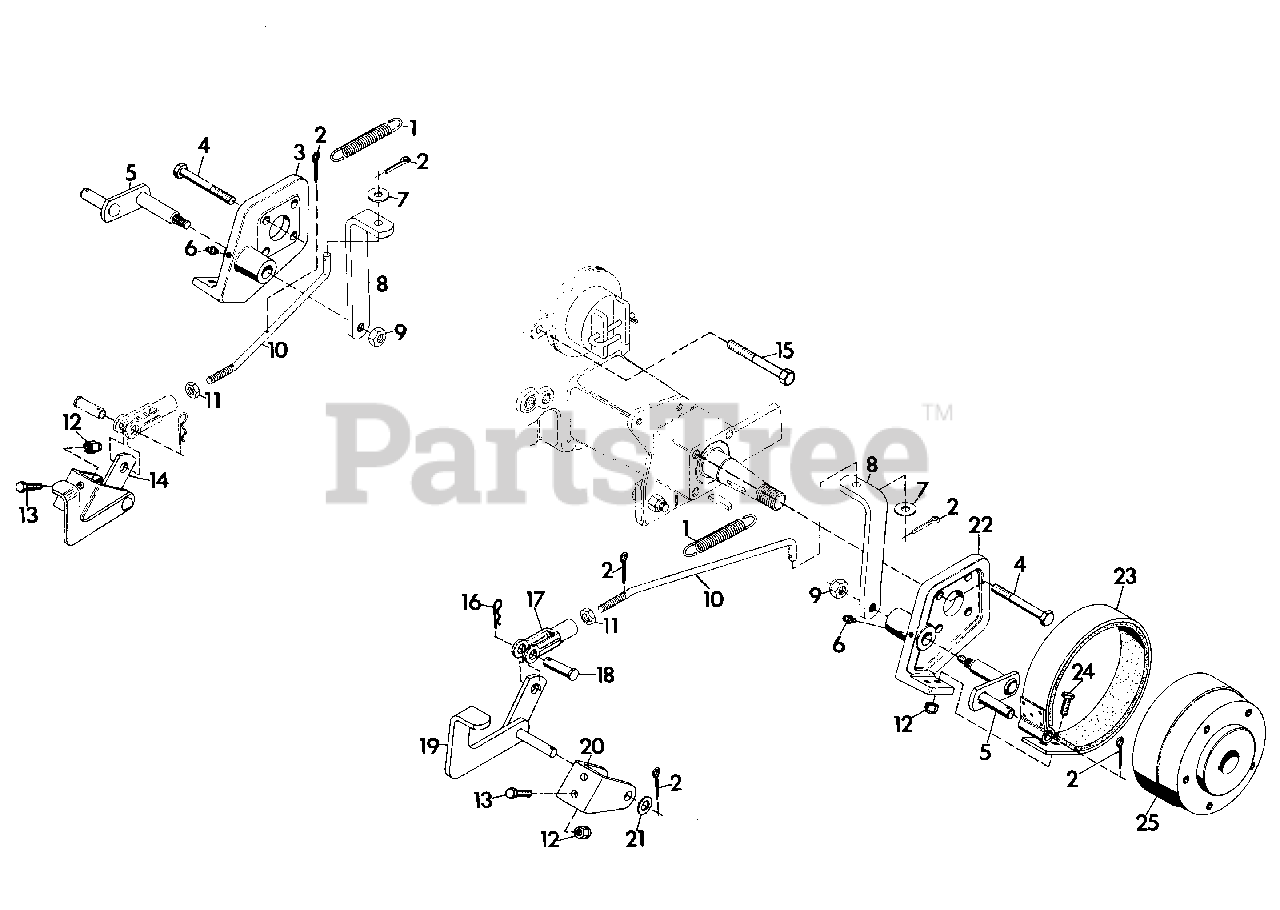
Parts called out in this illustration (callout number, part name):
1	SPRING
2	PIN, COTTER .094X.75
3	CASTING, R.H. BRAKE
4	BOLT, HEX 1/2-13X4.00
5	WELDMENT, PIN SHAFT
6	FITTING, LUBE 1/4-28
7	WASHER, FLAT .438X1.000X.083
8	LINK
9	NUT, LOCK 3/8-24
10	ROD, BRAKE
11	NUT, JAM 3/8-24
12	NUT, LOCK 5/16-18
13	BOLT, HEX 5/16-18X.75
14	WELDMENT, BRAKE PEDAL R.H.
15	BOLT, HEX 1/2-13X3.25
16	PIN, COTTER HAIR
17	CLEVIS, 3/8-24 ADJUSTABLE
18	PIN, CLEVIS .375X.948
19	WELDMENT, BRAKE PEDAL L.H.
20	BRACKET, BRAKE PEDAL
21	WASHER, FLAT .500X1.250X.083
22	CASTING, L.H. BRAKE
23	ASSEMBLY, BRAKE BAND
24	BOLT, HEX 5/16-18X1.25
25	DRUM, BRAKE
